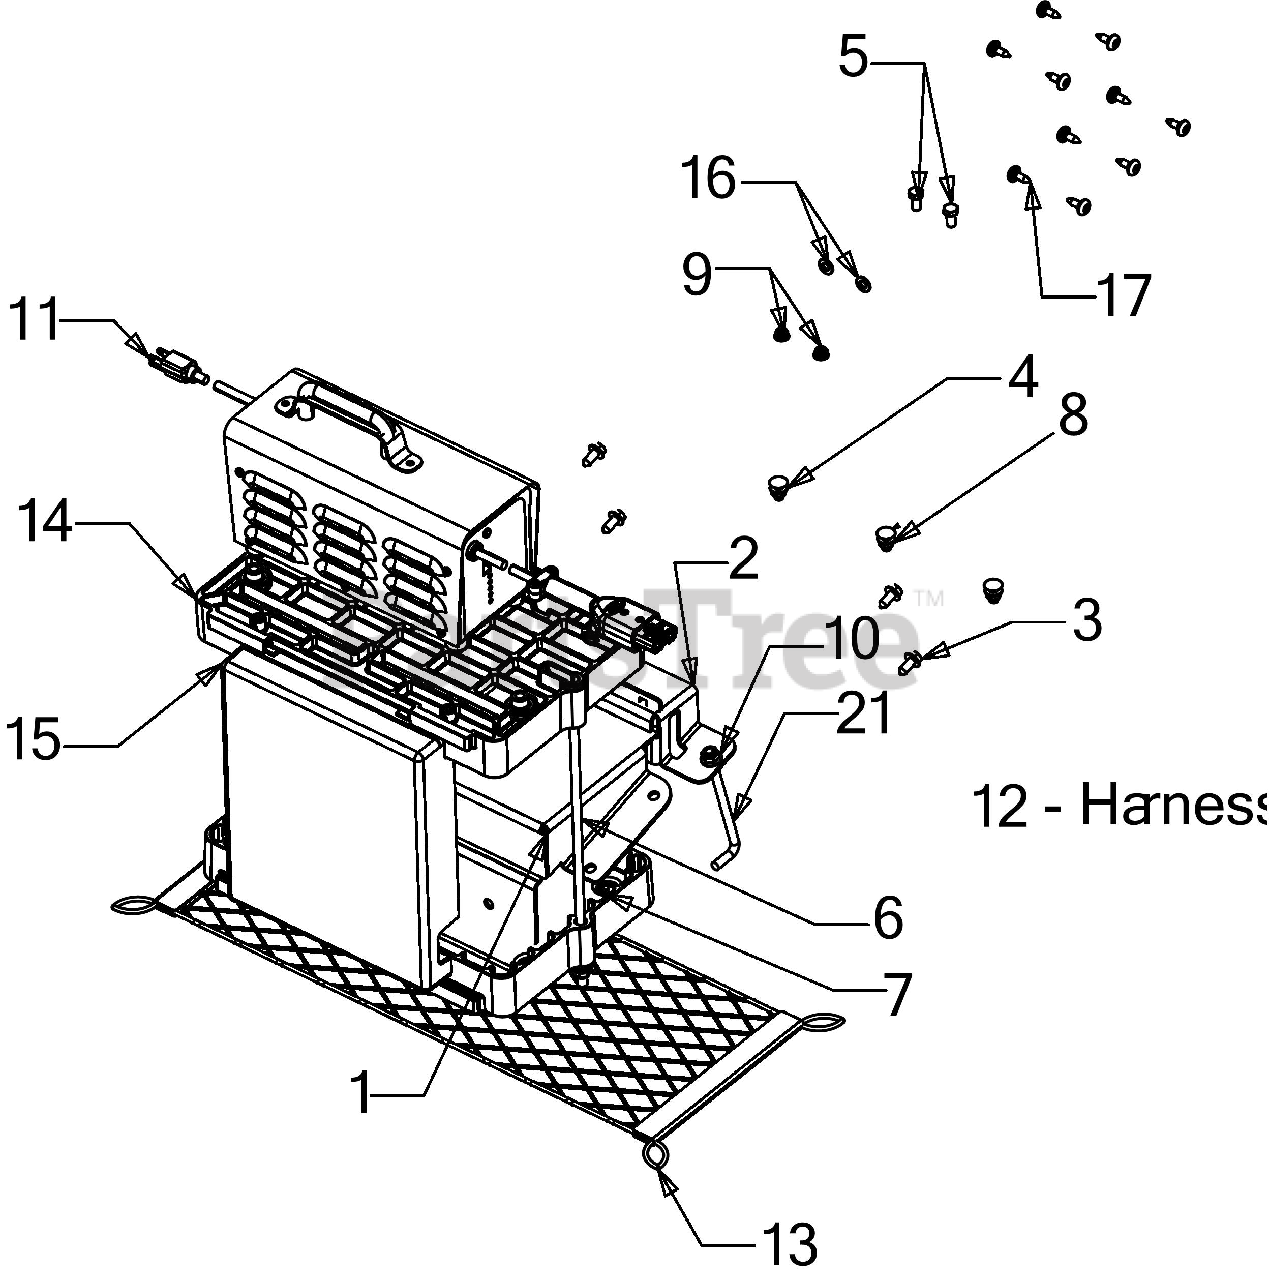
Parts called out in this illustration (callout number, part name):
1	FRONT BATTERY CLAMP
2	MIDDLE BATTERY CLAMP
3	SCREW 5/16-18 x .750
4	CARRIAGE BOLT 5/16-18 x .75
5	SCREW 5/16-18 x .62 GR5
6	BOLT 3/8-16
7	SCREW 5/16-18 x 1.00
8	FLANGE LOCK NUT 5/16-18
9	FLANGE LOCK NUT
11	BATTERY CHARGER
12	BATTERY CABLE
13	CARGO RETAINER
14	REAR BATTERY TRAY
15	BATTERY TERMINAL COVER
16	FLAT WASHER
17	TORX SHOULDER SCREW 1/4-20
21	BATTERY HOLD DOWN BOLT
